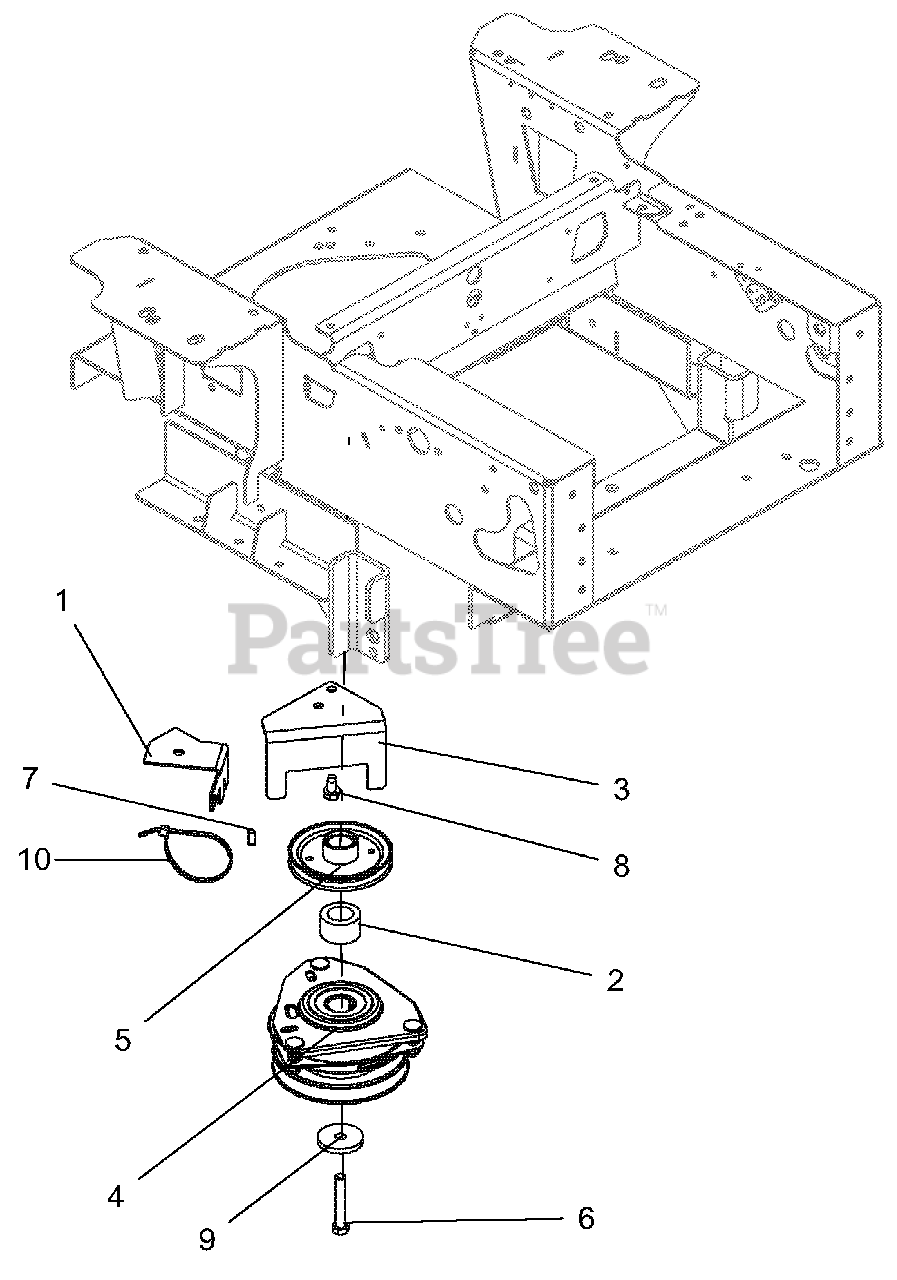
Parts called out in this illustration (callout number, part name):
1	HD CLUTCH WIRE GUARD - BLK
2	SPACER, 1.125 C 1.750 X 1.060
3	STOP, PRO-TURN CLUTCH-BLACK
4	CLUTCH, OGURA GT1A-EH01
5	PULLEY, 4.50 OD X 1.127 ENGINE-BLACK
6	BLT-HEX .44-20X2.75 GR5 EP80 YWZC
7	KEY-SQ .250X.250X.625
8	SCR-TAP .38-16X.75 HWH TR YWZ
9	WSHR-FL-STL .469X2.00X.25 YWZC
10	CABLE, TIE 5.50 LG
